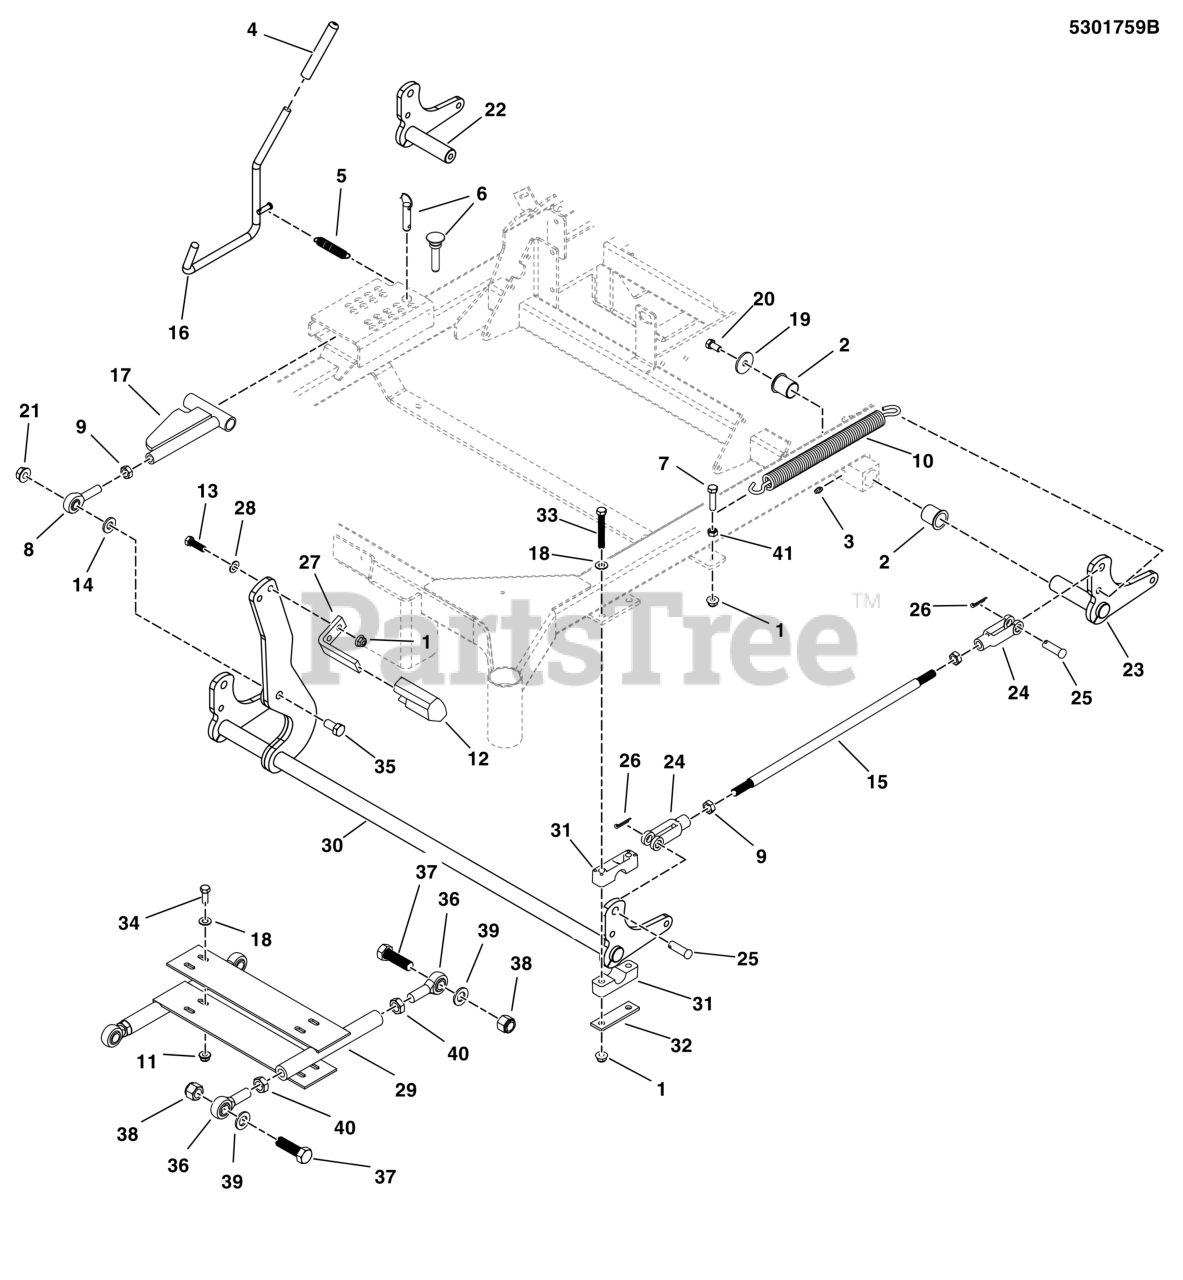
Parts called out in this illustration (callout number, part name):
1	NUT, 3/8 - 16 HEX NYLOCK FLANGE
2	BUSHING, 1.00 X 1.13 X 1.38, Plastic
3	GREASE FITTING, 1/4-28 Straight
4	GRIP, FOAM, .475 X 4.35 X .095
5	SPRING-EXT, .500 OD X 3.50 LG X .058 WR
6	PIN, HITCH, 1/2 X 2.0
6	LIFT, Deck
7	BOLT, 3/8-16 X 1-1/2" GD5 CZ
8	BALL JOINT, 1/2-20, MALE
9	NUT, 1/2-20 Hex Jam
10	SPRING-EXT, 1.00 ODX13.25LGX.177WR, BLK
11	NUT, 3/8-16 Hex Large Serrated Flange
12	PEDAL, Rubber
13	BOLT, 3/8-16 X 1-1/4" GD5 CZ
14	SPACER, .52 X 1.00 X .22, PM, CZ
15	ROD, DECK LIFT, 19.25, CZ
16	WELD, ROD DECK LIFT, F320Z - BLK
17	WELD, DECK ADJUST LINK - BLK
18	WASHER, 3/8 SAE
19	WASHER, .390 X 1.50 X .109, YZ
20	BOLT, 3/8-16 X 3/4, PLT W/PATCH
21	NUT, Hex Flange, Nylock, 1/2-13
22	WELD, PIVOT, DECK LIFT, RH - 210 - BLK
23	WELD, PIVOT, DECK LIFT, LH - 210 - BLK
24	CLEVIS, 1/2-20, STEEL, CLEAR ZINC
25	PIN, CLEVIS, 1/2 X 1-1/2, PLATED
26	* PIN, COTTER, 1/8" X 3/4
27	PEDAL, FOOT - BLK
28	WASHER, 3/8" GR. 9 FLAT
29	WELD, DECK STABILIZER, IS2500Z-246 - BLK
30	WELD, DECK LIFT SHAFT, 210Z-200XT - BLK
31	PIVOT BLOCK, PLASTIC
32	PLATE, PIVOT BLOCK SUPPORT - BLK
33	BOLT, 3/8-16 X 2-3/4" GD5 CZ
34	BOLT, 3/8-16 X 1" GD5 CZ
35	BOLT, 1/2-13 X 2-1/4" GD5 CZ
36	BALL JOINT, 3/4-16, MALE
37	BOLT, 3/4-16 X 2-1/2" YZ GD5
38	NUT, Hex, Nylon Lock, 3/4-16
39	WASHER, 3/4 SAE
40	NUT, Hex, Jam, 3/4-16
41	NUT, 3/8-16 HEX JAM
